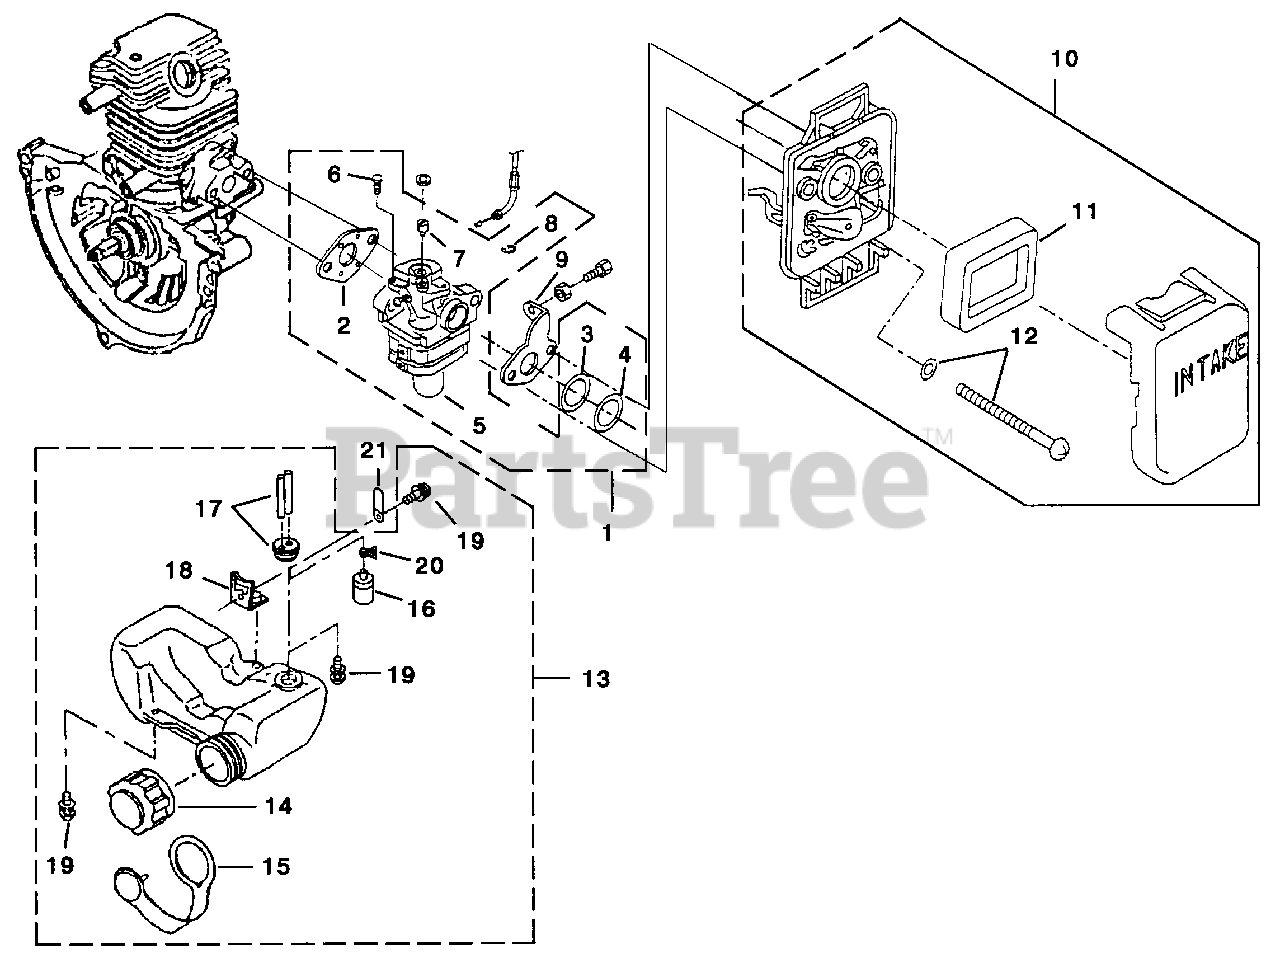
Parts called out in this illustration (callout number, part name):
1	CARBURETOR ASSEMBLY
2	GASKET-Carburetor
5	PRIMER BULB
6	SCREW, COLLAR THROTTLE
9	BRACKET-Cable
10	AIR FILTER ASSEMBLY
11	AIR FILTER
12	SCREW ASSEMBLY (M5 x 65)
13	FUEL TANK ASSEMBLY
14	CAP-Fuel
15	RETAINER-Fuel Cap
16	FILTER-Fuel
17	FUEL LINE ASSEMBLY
18	BRACKET-Fuel Tank
19	SCREW ASSEMBLY (M5 x 16)
20	CLAMP-Hose
